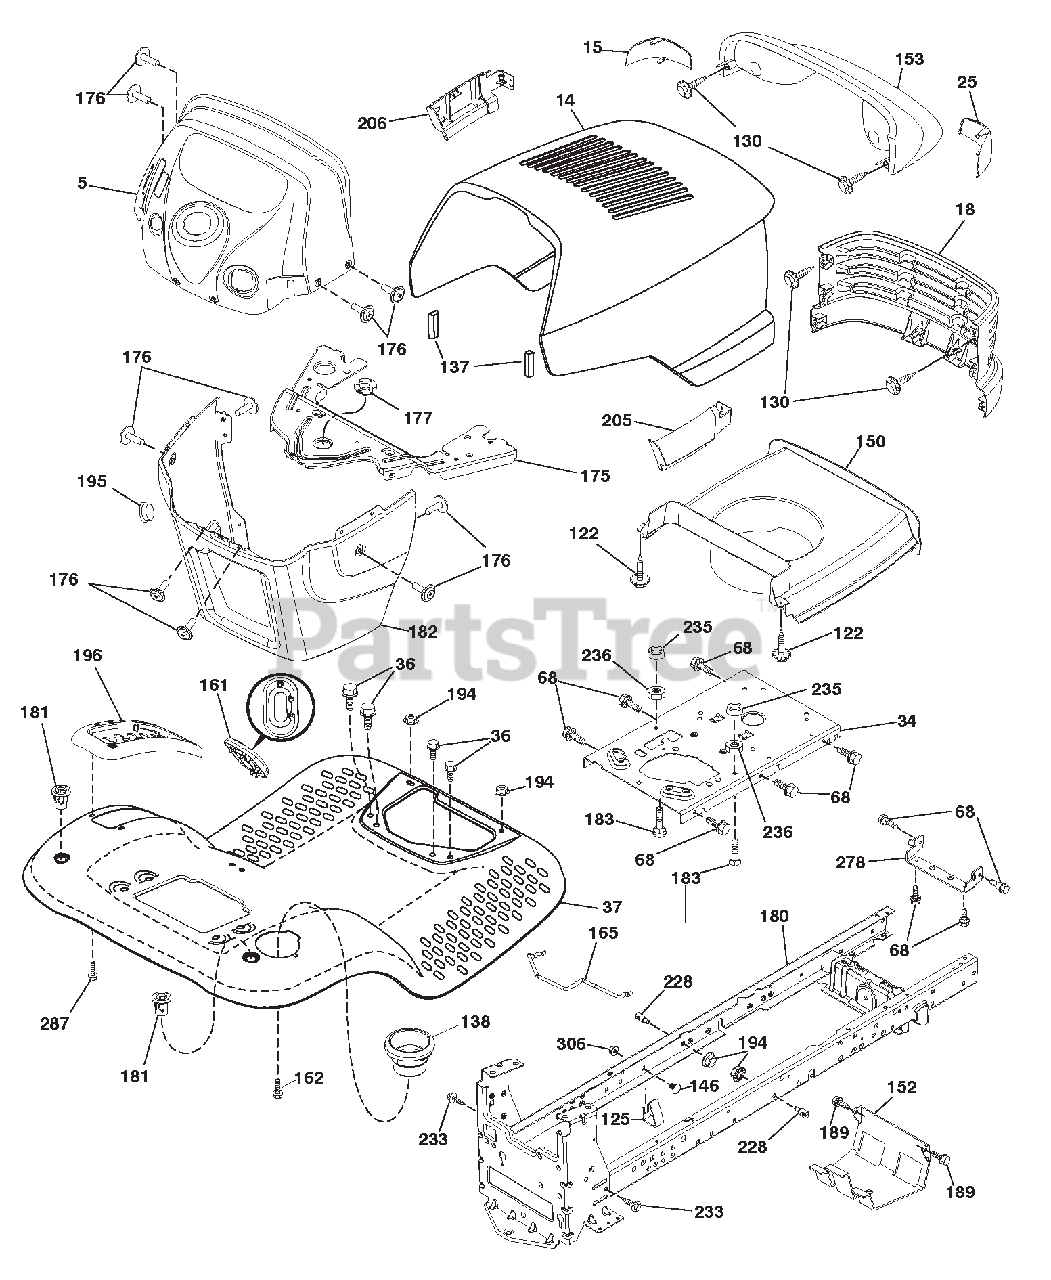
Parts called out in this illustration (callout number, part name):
15	LENS ELITE ARIENS BLACK
25	LENS ELITE HUSQ CLEAR RH
34	PLATE ENGINE WELDED CHASSIS
36	SCREW.5/16-18X3/4.SMGML.TAP/R
68	SCREW.THDROL.5/16-18 X 1/2TYTT
122	SCREW TO 32 X 5/8
125	CLIP.FUEL.LINE
137	BUMPER HOOD LARGE 1.75
138	CUPHOLDER TL TEX 428
150	DUCT AIR ENGINE
151	BRACKET PIVOT LASR/ELTE/HUSQLT
152	SHIELD.BROWNING.W/TEX
153	ASM LIGHT BOX
161	WINDOW FUEL
162	SCREW.HEX.WSH.HI-LO.1/4X1/2UNC
165	SUPPORT.TANK.REAR.W/TEX
175	CROSSMEMBER LT
176	SCREW.#10-24X5/8.RND.QUDRX.GIM
177	BUSHING.STEERING.YT/GT
180	CHASS WLDMT TL 12 GA/2PC 18/22
181	BUSHING MNT FEND CRGO BLK TEX
182	DASH TOWER LT CCS
183	BOLT.FIN.HEX.5/16-18 UNC X1-1/
189	SCREW.5/16-18X3/4.SMGML.TAP/BL
194	Nut, Lock Hex Flange 5/16-18 u
195	PLUG HOLE DASH TOWER
196	CONSOLE ASM.DECKLFT.BL/RBT.TLT
205	SKIRT SIDE RH
206	SKIRT SIDE LH
228	STUD.FASTNER.W/'D'ANTI-ROTATIO
233	BOLT.SHOULDER
235	SPACER.FENDER
236	NUT.CENTER LOCK.5/16-18 UNC
278	X-PIECE HOOD
287	SCREW.HEX.WASHEAD.1/4-20 X 3/8
306	Nut, Hex, Flangelock 3/8-16
